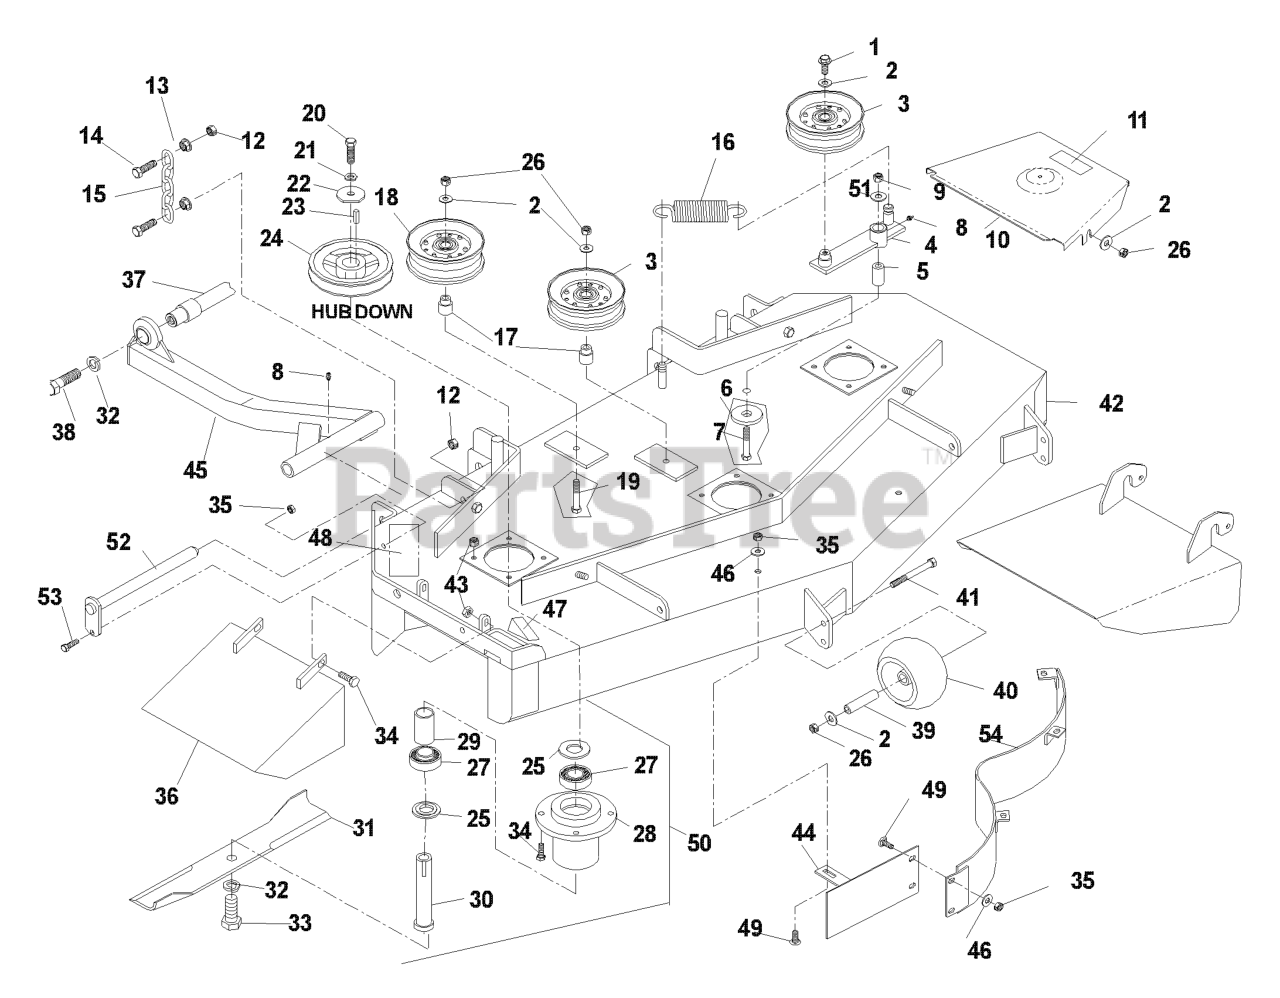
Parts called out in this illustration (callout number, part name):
1	4CS 3/8C X 1 SERRATED HEAD
2	WASHER 3/8 FLAT
3	IDLER PULLEY
5	PIVOT BUSHING
6	WASHER, SUPPORT
7	HCS 1/2C X 3 1/4
8	ZERK
9	NUT 1/2-13 HEX NYLOC ZD
10	BELTSHIELD
11	DECAL, NO STEP
12	NUT 7/16C CENTERLOCK
13	NUT 7/16C WHIZ
14	HCS 7/16C X 1 1/2
15	LIFT CHAIN
17	IDLER BUSHING
18	IDLER PULLEY (TALL)
19	SCREW 3/8C X 2 3/4 HEX CAP
20	HCS 7/16F X 1 1/2
21	WASHER 7/16 LOCK
22	SPINDLE WASHER
23	KEY 1/4 SQ X 1 1/8
25	COMBO SPACER
26	NUT 3/8-16 NYLOC
27	BEARING
28	HOUSING, DIE CAST
30	SPINDLE SHAFT
31	BLADE OEM 16 1/4"
32	LOCKWASHER 5/8
33	HCS 5/8F X 1 1/4
34	HCS 5/16C X 1 1/4
35	NUT 5/16C CENTERLOCK
36	DEFLECTOR CHUTE
37	STRUT MOUNT WELDMENT
38	HCS 5/8C X 2 GR.5
40	ANTI-SCALP ROLLER
41	HCS 3/8C X 3 1/2
42	DECK W/DECALS 48"
43	NUT 5/16 NYLOC
44	CENTER BAFFLE 48"
45	STRUT WLDMT - RT
46	WASHER 5/16 FLAT
47	DECAL, CPSC
48	DECAL, DANGER
49	CARRIAGE BOLT 5/16C X 5/8"
50	HOUSING, COMPLETE
51	WASHER 1/2 FLAT
53	HCS 5/16C X 3/4
54	MAIN BAFFLE - 48" DECK BLK
